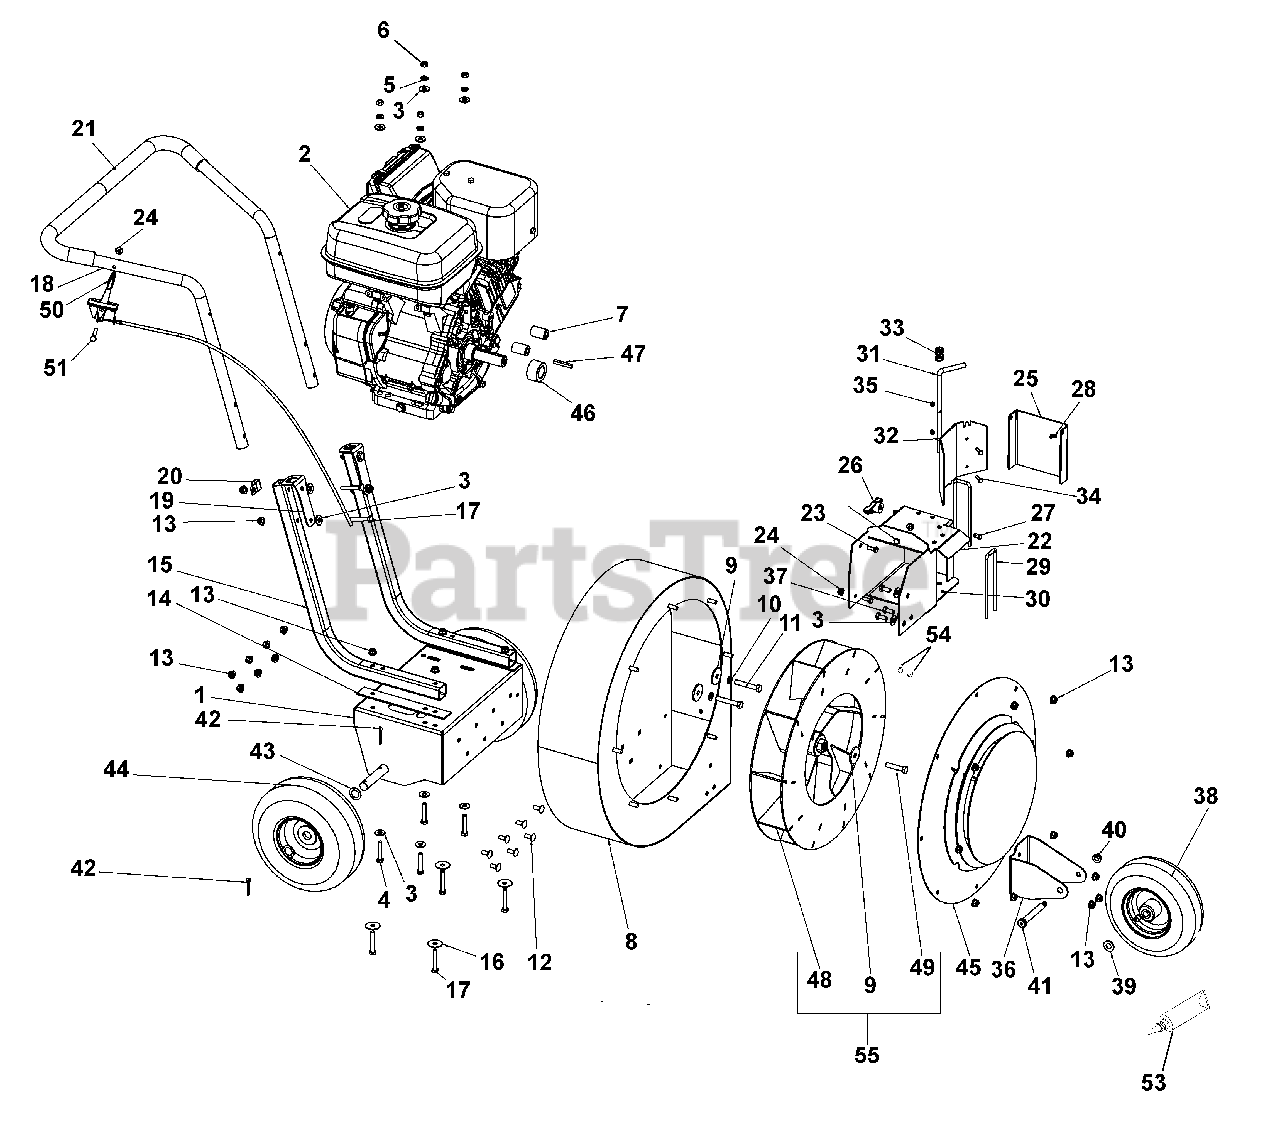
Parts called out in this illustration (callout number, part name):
1	Weldment, Blower Frame LG
2	Engine, SUBARU 14HP EX40 (CARB)
3	Washer, Flat Steel .38 x .875 x .083
4	Bolt, Hex .31-18 x 1.75 Grade 5
5	Washer, Locking .312 x .097 Heavy
6	Nut, Hex .31-18
7	Engine Spacer
8	Weldment, Blower Housing LG
9	Washer, Flat Steel .380 x 1.50 x .125
10	Washer, Locking .38 x .094 Regular
11	Bolt, Hex .38-16 x 2.25 Grade 5
12	Bolt, Round Head Square Neck .31-18 x .75 Grade 5
13	Nut, .31-18 Nyloc Flange
14	Rubber Spacer
15	Handlebar, Lower
16	Washer, Flat Steel .347 x 1.254 x .048
17	Bolt, Hex .31-18 x 2.00 Grade 5
18	Tube, Handlebar, Upper
19	Bracket, Handlebar Mount
21	Grip, Handlebar, Upper
22	Weldment, Outlet Chute LG
23	Bolt, Hex .25-20 x .75 Grade 5
24	Nut, .25-20 Nyloc Flange
25	Bracket, Cap, Chute LG
26	Knob, Wing .31-18 UNC
27	Pin, Clevis .313 x .500
28	Pin, Hair
29	Wireform, Guard, Safety
30	Push, Nut 1/4
31	Wireform, Lever, Direction
32	Bracket, Deflector, Air Baffle
33	Spring, Compression 1.0L x .72 OD .05DIA
34	Screw, Machine 10-24 x .75 Hex Washer Head
35	Nut, Locking Nylon 10-24 with Insert
36	Bracket, Wheel, Front
37	Bolt, Hex .31-18 x .75 Grade 5 YWZC
38	Wheel, 9 x 2.5 PNEU-Grey Rim
39	Washer, Flat Nylon .52 x 1.00 x .08
40	Nut, Locking-Top-Flange .38-16
41	Bolt, Shoulder .5 x 3.25 x .38-16
42	Pin, Cotter .16 x 1.25 Extended Prong Square Cut
43	Washer, Flat Steel .754 x 1.125 x .062
44	Wheel, 10 x 3.75 Grey
45	Weldment, Inlet Guard LG
46	Bushing, Sleeve, 1.0 x 2.0 x 1.0
47	Key, Square .25 x 1.75 x .25
48	Weldment, Fan, Blower LG
49	Bolt, Hex .38-24 x 1.75 Grade 8
50	Throttle Control
51	Bolt, Hex .25-20 x 2.00 Grade 5
52	Washer, Flat Steel .390 x .88 x .18
53	Loctite 609® .5 ml
54	Set Screw .31-18 x .38
55	Kit – 14hp Fan Replacement
